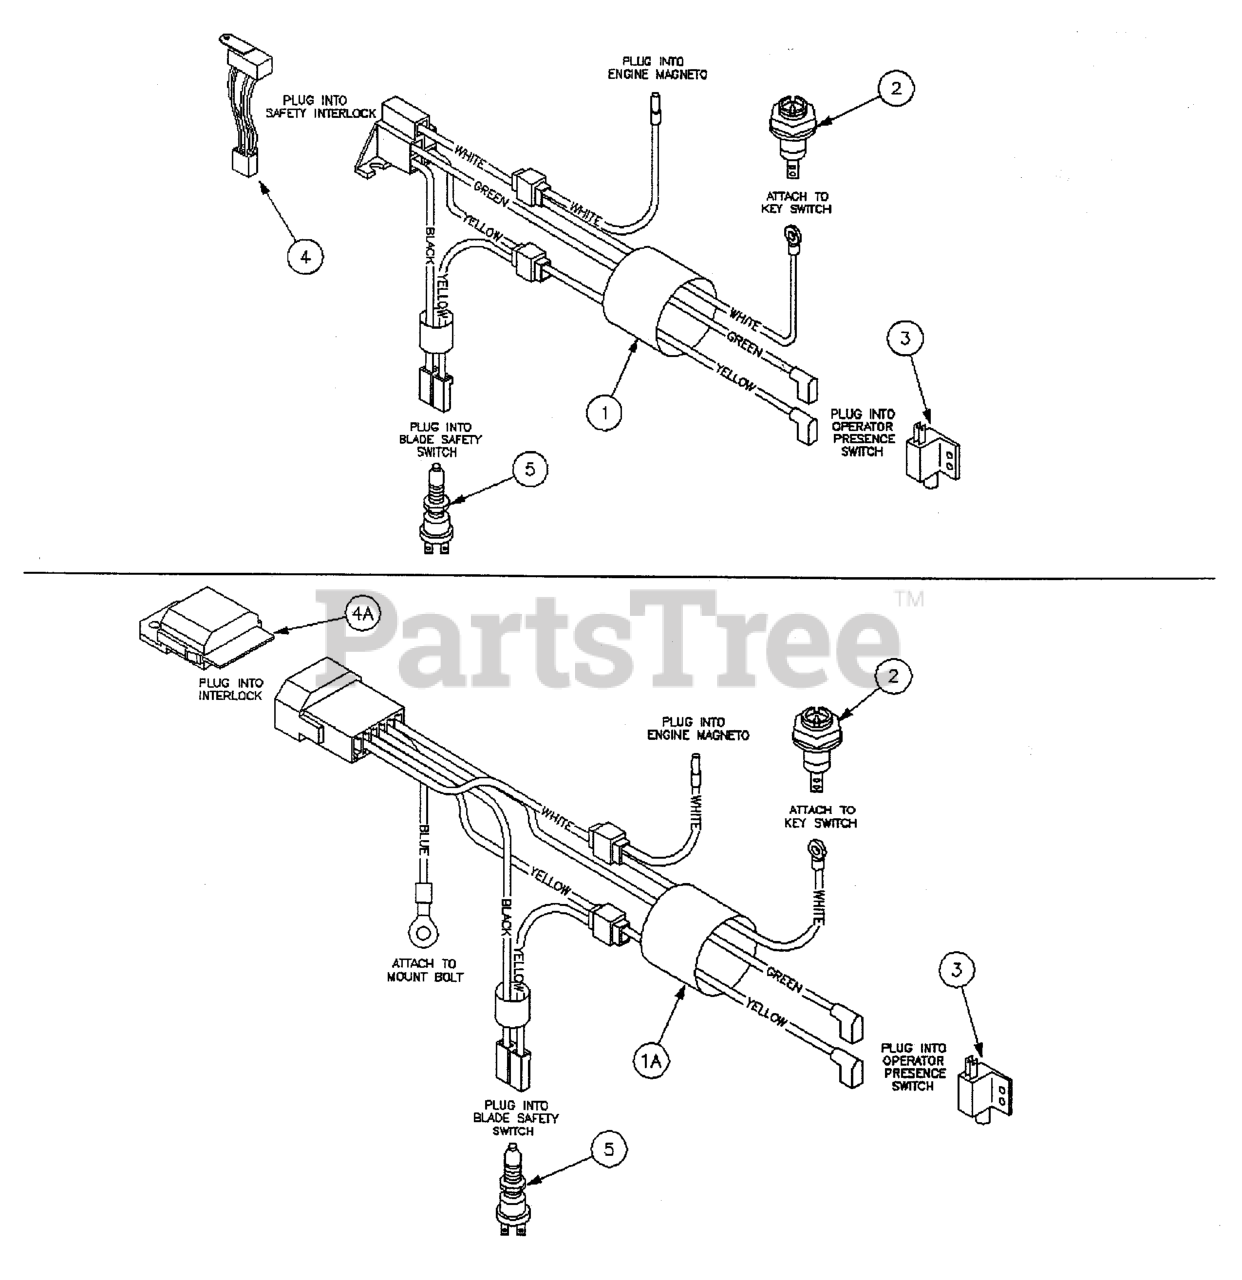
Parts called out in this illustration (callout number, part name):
1	Main Harness
1A	HW Kawasaki Wire Harness
2	SWITCH, Ignition
3	SWITCH, Plunger, NO
4	Saftey Interlock
4	Interlock
4A	Interlock
5	SWITCH, Plunger, NO
